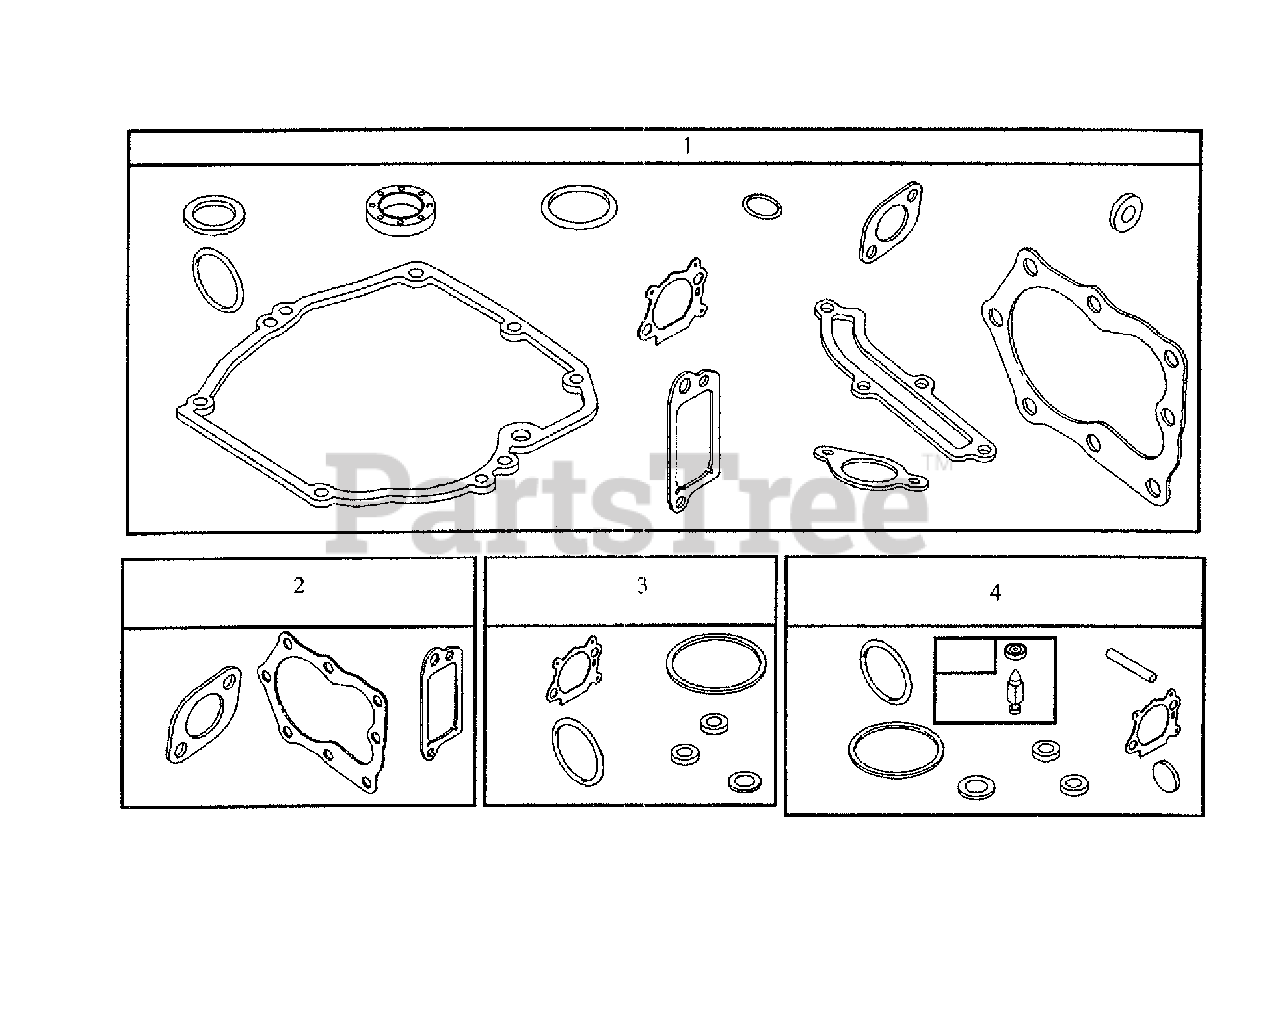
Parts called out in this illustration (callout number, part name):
1	Gasket Set Engine
2	Gasket Set Valve
3	Gasket Set Carburetor
4	Kit, Carburetor
